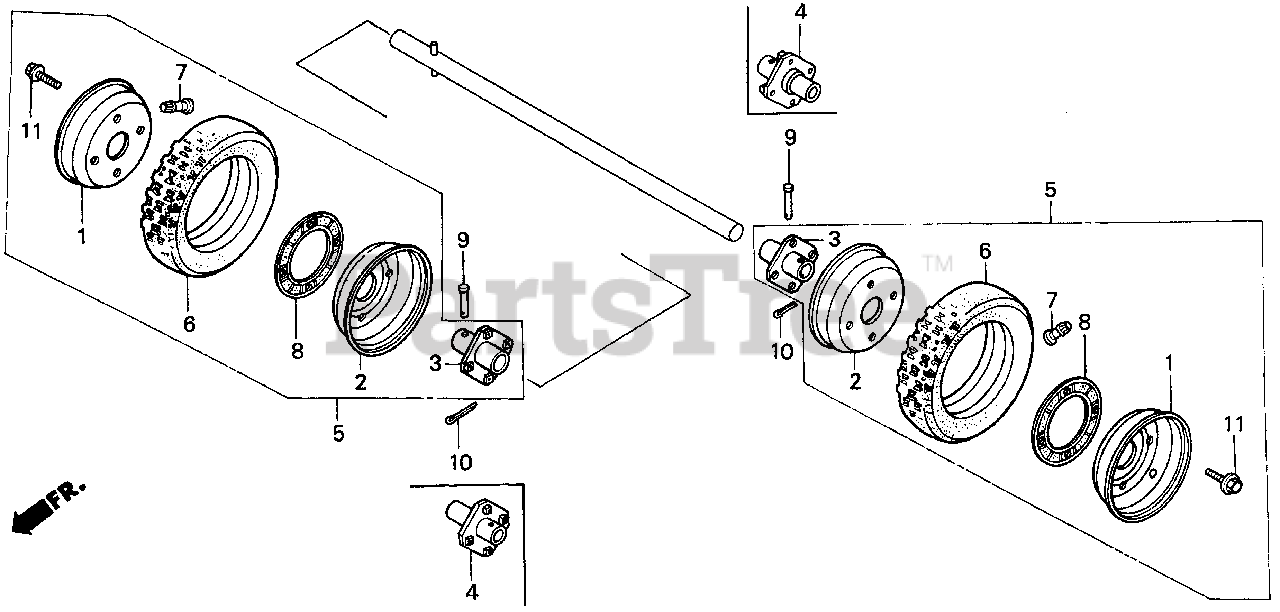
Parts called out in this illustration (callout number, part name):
1	WHEEL A (3SPWX6DCT)
2	WHEEL B (3SPWX6DCT)
4	WHEEL (HUB NOT AVAILABLE: IS PART OF COMPLETE WHEEL 42710-V41-003)
6	TIRE (14X4.00-6)
6	TIRE (14X4.0-6)
7	VALVE, RIM (SCHRADER)
7	VALVE, RIM (TAIHEIYO)
8	GASKET (U-75)
10	PIN, SPLIT (3.0X18)
11	BOLT, FLANGE (8X16)
